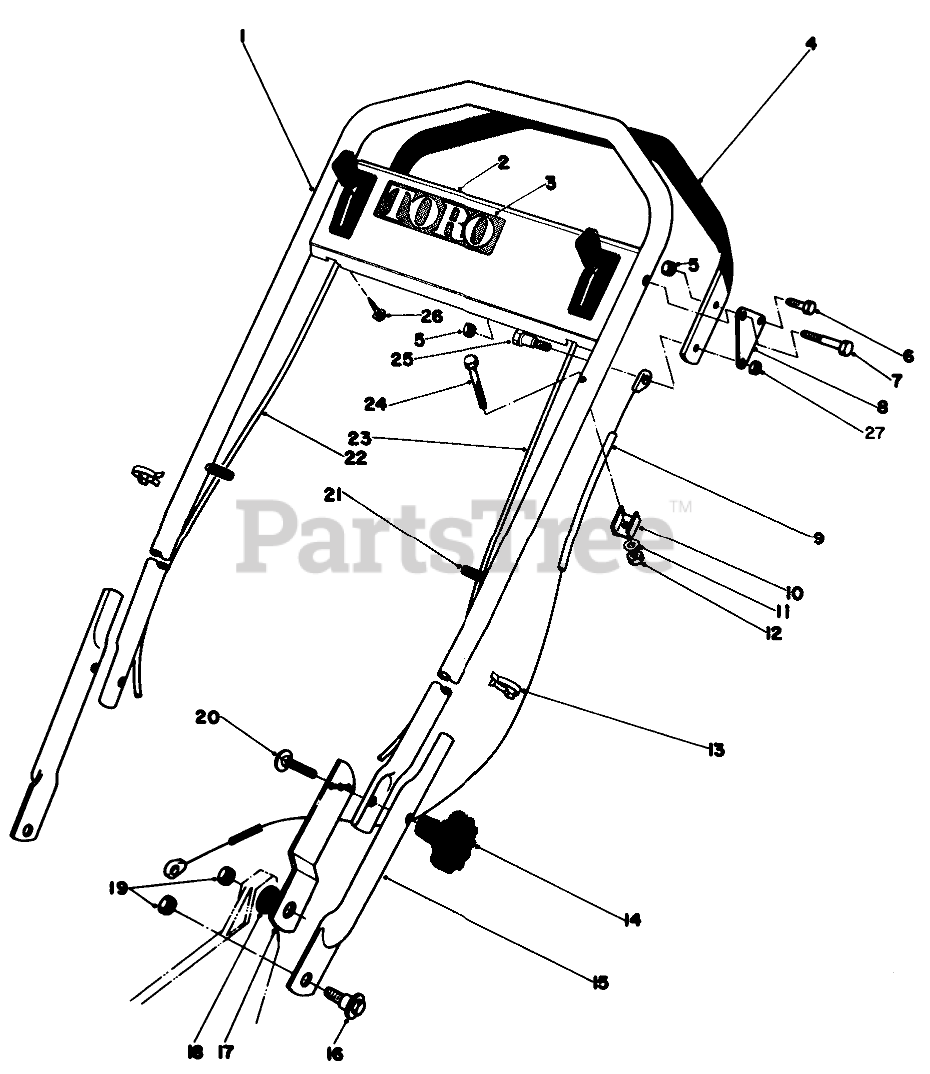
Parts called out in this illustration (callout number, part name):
1	Upper Handle
2	Control Plate
3	Decal-Toro
4	DEMAND HANDLE ASM
5	NUT-LOCK, CONE
6	SCREW-HH
7	BOLT-SHOULDER
8	Bracket Demand
9	DEMAND HAND CABLE
10	CLAMP-CABLE
11	WASHER-FLAT
12	NUT-LOCK, NI
13	BOWDEN CLIP
15	LOWER HANDLE
16	SCREW-SHOULDER
17	Handle Latch L.H.
18	SPACER
19	Nut
20	SCREW-CARR
21	CAP-VINYL
22	Ground Speed Control
23	Throttle Control
24	SCREW-HH
25	Shoulder Bolt
26	SCREW-HWHTF
27	NUT-HEX, SIDE DEFORM
